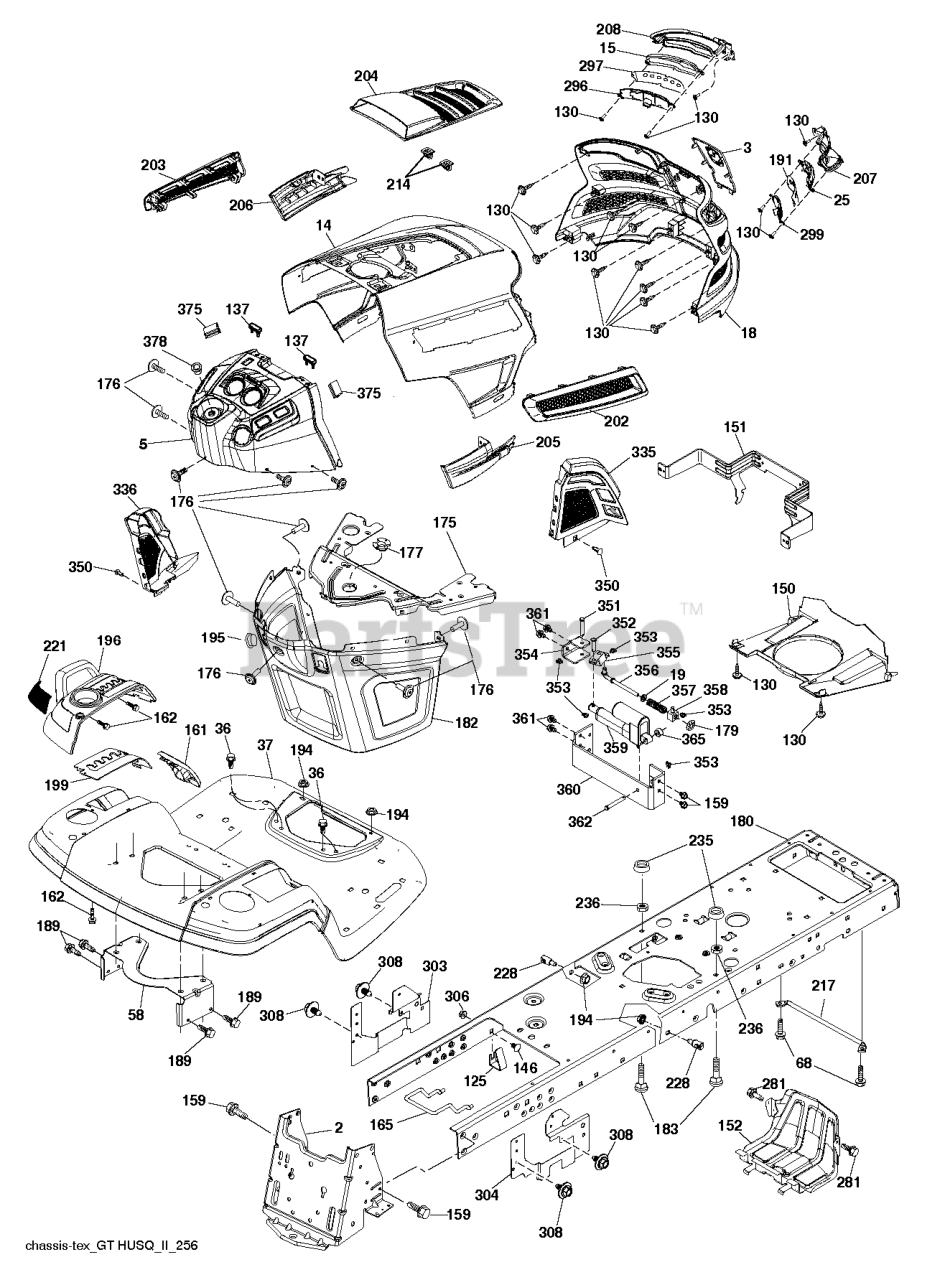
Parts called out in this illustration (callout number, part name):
2	DRAWBAR.STGT
3	APPLIQUE.SUBASM.GT.HUSQ.II
5	DASH.GT2.UPPER.RND.ELD.CP.498
14	HOOD.ASM.HUSQVARNA.GT.TEX.ORAN
15	LED LIGHT.LH
18	GRILLE SUBASM.GT.II.LOW.HDLGHT
19	WASHER
25	LENS.RH
36	SCREW 5/16"
37	FENDER.PNT.TX.GT.CH/FW/DL.HUSQ
58	BRKT.SUPPORT.FNDR/TANK
68	SCR 5/16-18 X 1/2 SELFTAP ZN
125	CLIP.FUEL.LINE
130	SCREW.#10 X 0.750.BOS
137	BUMPER DASH
146	BOLT.RDHD.SHT.SQNK.3/8-16X5/8
150	AIR.DUCT.GTV.BLACK
151	BRACKET.PIVOT.HOOD.GT.HUSQ.II
152	SHIELD.BROWNING.PNT.GT.V2
159	SCREW, 3/8-16X3/4
161	CONSOLE.WINDOW.FUEL.HUSQ.GT
162	SCREW.HI-LO.CONSOLE
165	SUPPORT.TANK.REAR.B/TE
175	PLATE.PNT.CROSSMEMBER.HUSQ/PRE
176	SCREW.#10-24X5/8.RN.QU
177	BUSHING STEERING
180	CHASSIS LTGT BOLTED PAINTED X4
182	DASH.LOWER.COMMON.12V.ADAPTOR
183	BOLT.5/16-18X1-1/4 FULL THD
189	SCREW
191	INSERT INFLECT.RH
194	NUT LOCK HEX FLANGE 5/16-18
195	PLUG.HOLE.DASH.LOWER.12V.BLK
196	CONSOLE.ASM.DECKLIFT.HUSQGT.DL
199	PLATE.DECK.LIFT.HUSQVARNA.GT
202	VENT.SIDE.RH.GT.HUSQ.II.
203	VENT.SIDE.LH.GT.HUSQ.II.498
204	VENT.TOP.ASM.HUSQ.GT2
205	SIDE.TRIM.RH.GT.HUSQ.II
206	SIDE.TRIM.LH.GT.HUSQ.II.GRAY
207	BEZEL GT2 LED RH W/ LOWER.ATT
208	BEZEL GT2 LED LH W/ LOWER ATT
214	CLIP.RETAINER.TINNER.
217	ROD.PIVOT.HOOD
221	REFLECTOR.LH.TEX GT HU
228	STUD.FASTNER.W/ANTI-ROTATE
235	SPACER FENDER
236	NUT.CENTERLOCK.5/16-
281	SCREW 3/8-16X1
296	LED LIGHT.LH
297	INSERT REFECT LH
299	LED LIGHT.RH
303	SHIELD.LWR.LH.LTGT.NON30
304	SHIELD.LWR.RH.LTGT.NON30.NOTCH
306	NUT LOCK FLG 3/8-16 UNC
308	BOLT.5/16-18UNCX3/4 W/SEMS.BLK
335	COVER.LOWER.DASH.RH.BLACK
336	COVER-LH.LOWER.DASH.GT2.BLACK
350	CLIP.X-MAS.TREE
351	PIN.CLEVIS.375X2.125
352	PIN.CLEVIS.(.375 X 1.25)
353	CLIP RETAINER
354	SUPPORT.BELLCRANK
355	BELLCRANK.PIVOT.LOCK.DIFF
356	LINK.LOCK.DIFF
357	SPRING.COMPRESSION
358	GUIDE.SWIVEL
359	ACTUATOR.ELECTRIC
360	BRACKET.ACUATOR
361	SCREW LT.3/8-46X5/8
362	PIN.CLEVIS.(.375 X 2.42)
365	SPACER.NYLON.75" X .4375
375	BUMPER CLIP-ON. DASH 1"
378	BUSHING FLANGE; PLASTIC
